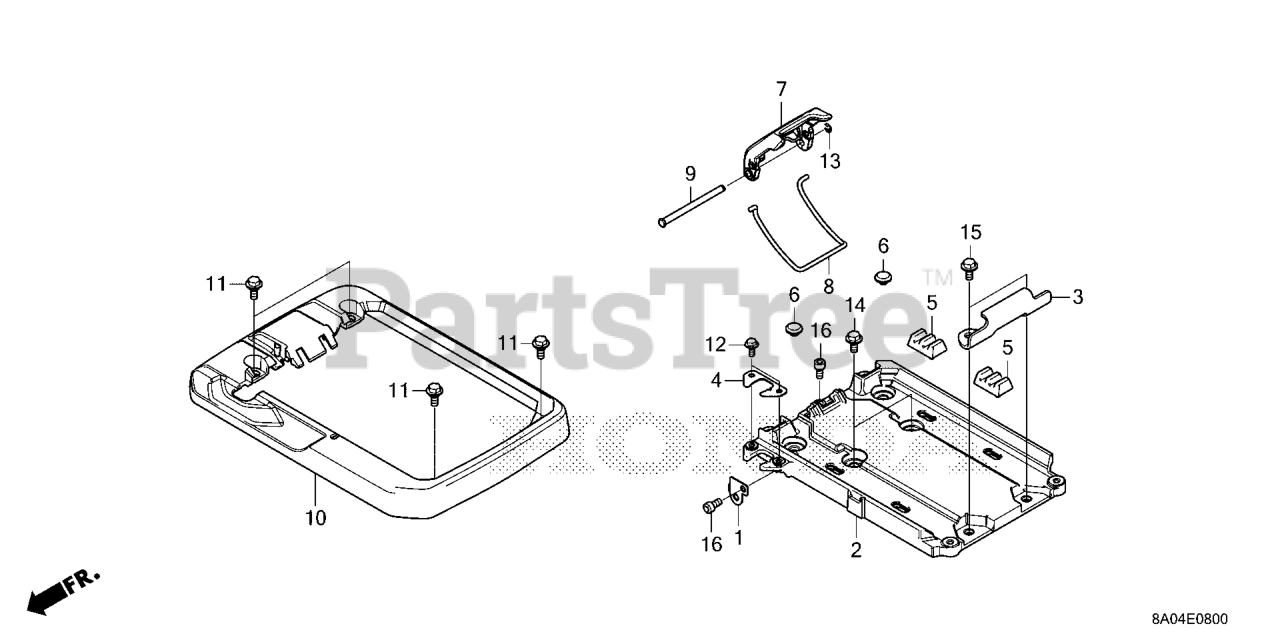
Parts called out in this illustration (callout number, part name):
1	BRKT, HARNESS CLIP A
2	TRAY, BATTERY
3	HOOK, BATTERY
4	STAY, CONNECTOR
6	CAP, HOLE (8MM)
7	LEVER *NH283*
8	WIRE, FASTENER
9	PIN, LOCK LEVER
10	COVER *R280*
10	COVER *NH1*
11	BOLT, SPECIAL (6X16)
12	BOLT, FLANGE (5X12)
13	E-RING (4MM)
14	BOLT, FLANGE (8X16)
15	BOLT, FLANGE (8X20)
16	BOLT, SOCKET (6X12)
